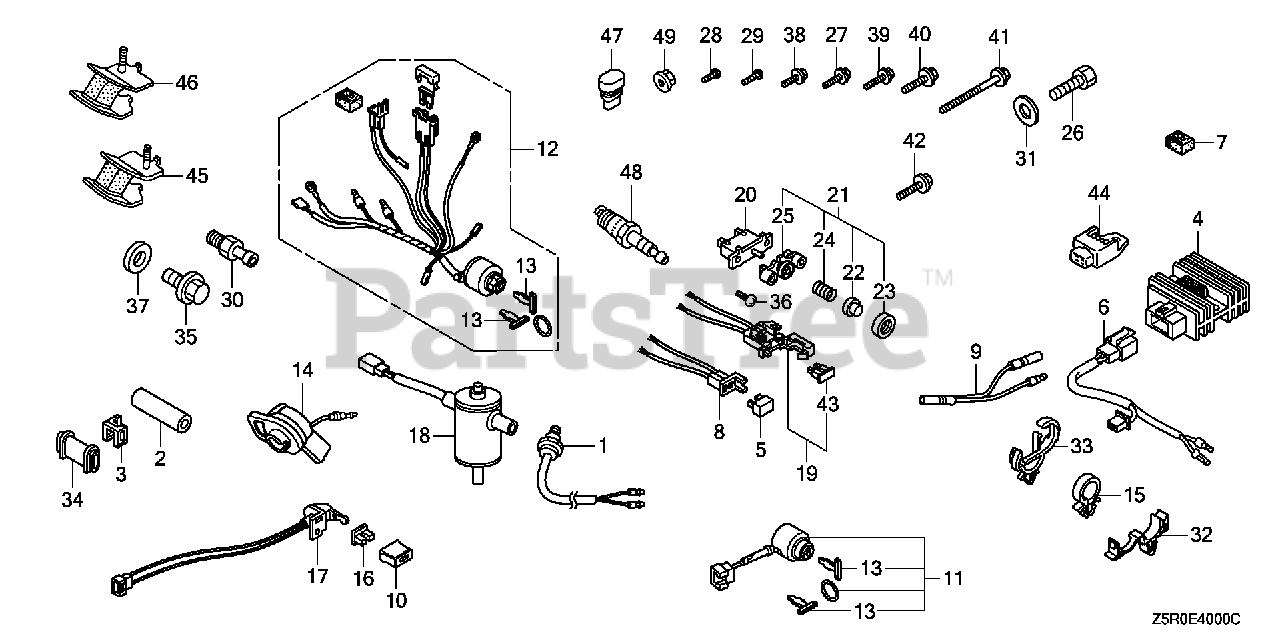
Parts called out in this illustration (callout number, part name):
7	SUSPENSION, CONNECTOR
12	SWITCH ASSY., COMBINATION (3A-CHARGE)
13	KEY (HONDALOCK)
18	VALVE ASSY., SOLENOID
43	FUSE, BLADE (15A)
